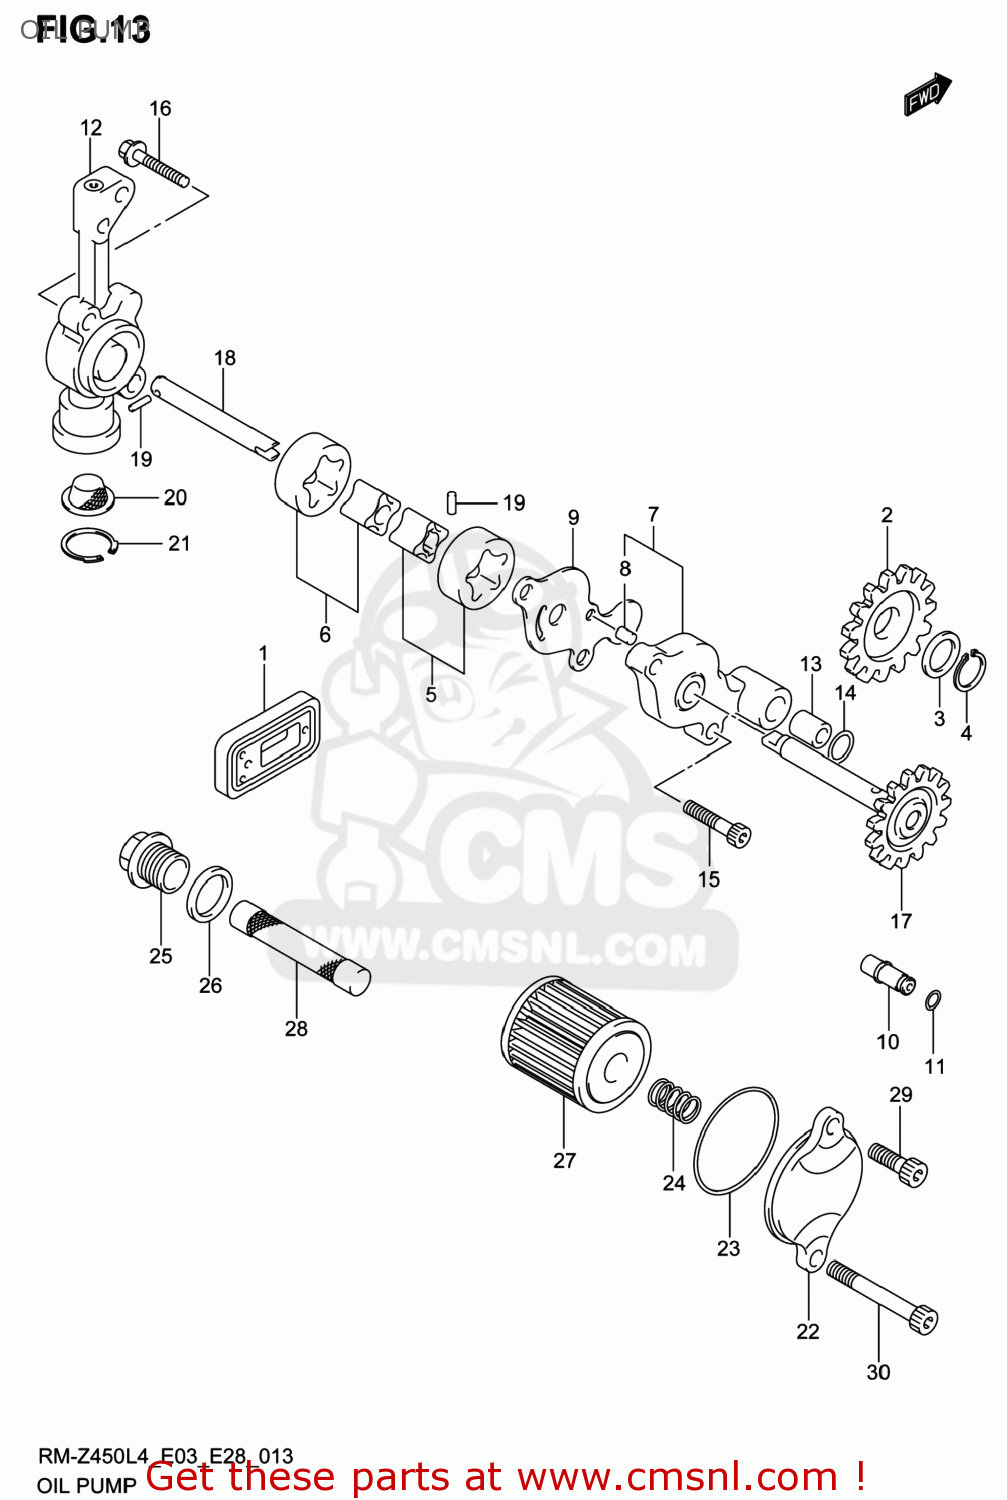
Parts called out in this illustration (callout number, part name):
1	VALVE ASSY,OIL REED
2	GEAR,OIL PUMP IDLE
3	SHIM(12X18X0.5)
4	CIRCLIP
5	ROTOR SET,OIL PUMP NO.1
6	ROTOR SET,OIL PUMP
7	COVER,OIL PUMP NO.1
8	PIN
9	PLATE,OIL PUMP NO.1
10	VALVE ASSY,OIL RELIEF
11	O RING(D:1.2,ID:4.7)
12	COVER,OIL PUMP NO.2
13	PIN
14	O RING(D:1.9,ID:8.6)
15	BOLT
16	BOLT
17	SHAFT,OIL PUMP DRIVEN GEAR
18	SHAFT,OIL PUMP NO.2
19	PIN(2.5X11.8)
20	STRAINER,OIL PUMP NO.2
21	CIRCLIP
22	CAP,ENG OIL FILTER OUTER
23	O RING(D:2,ID:38.5)
24	SPRING
25	CAP,ENG OIL STRAINER
26	GASKET(16X22X2) (NAS)
27	FILTER ASSY,ENGINE OIL
28	STRAINER,ENGINE OIL
29	BOLT
30	BOLT
